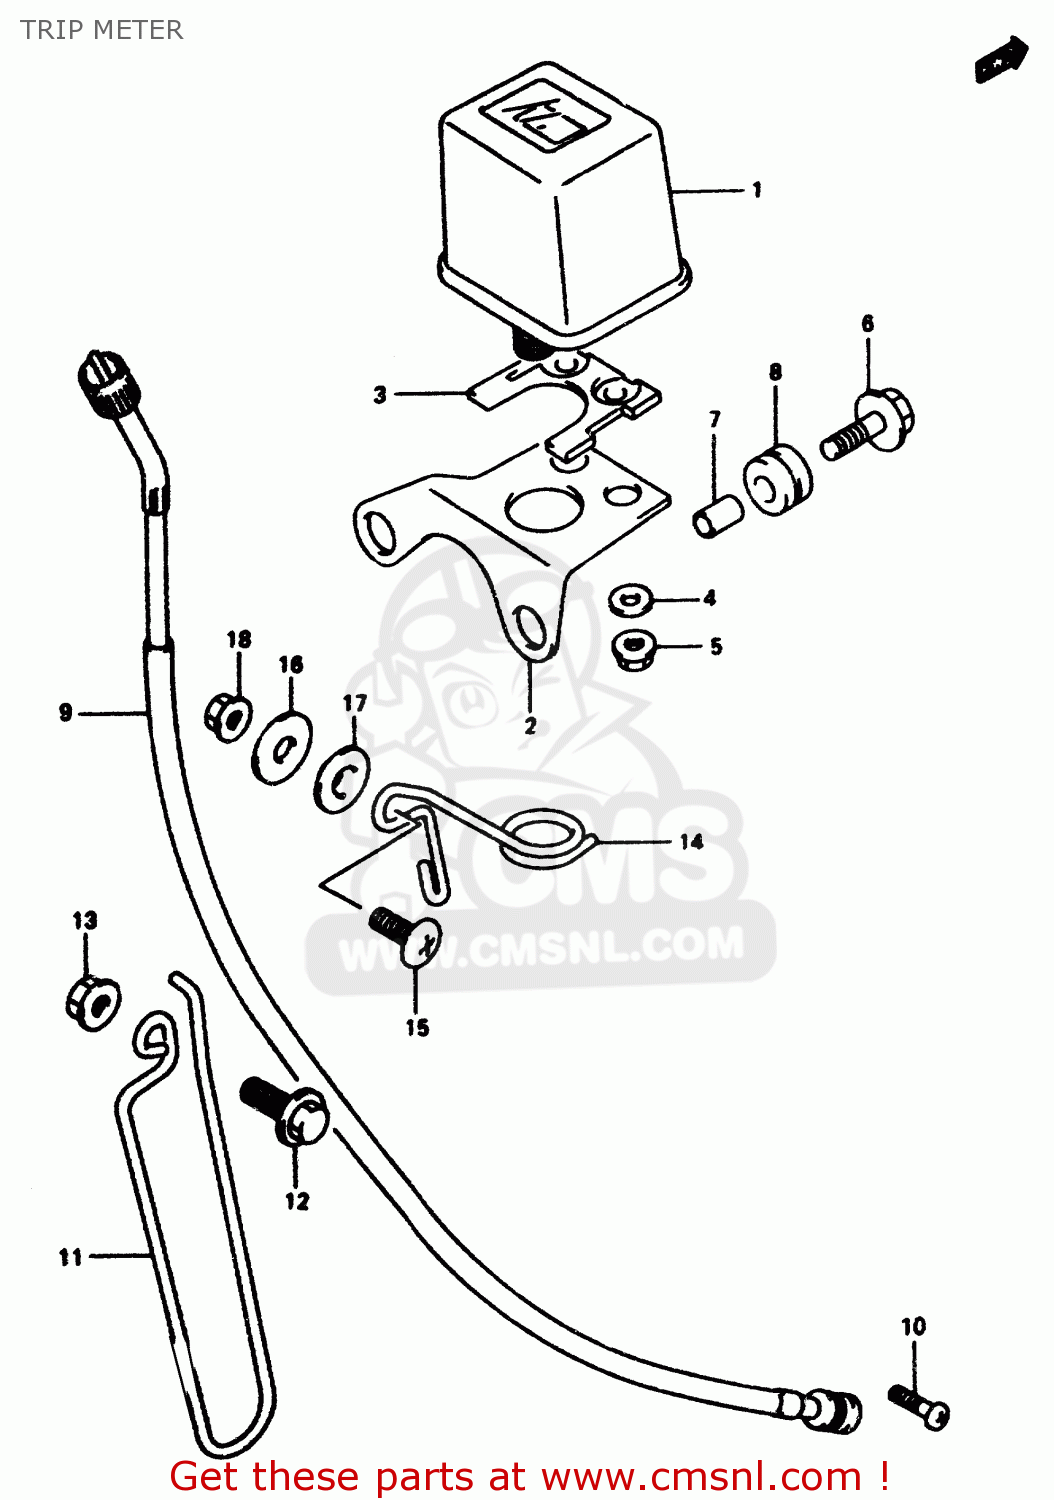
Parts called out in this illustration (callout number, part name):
1	TRIP METER
2	BRACKET
3	CUSHION
4	WASHER (4.3X13X0.80)
5	NUT
6	BOLT(6X25)
7	SPACER(6.1X8X9.5)
8	CUSHION
9	CABLE ASSY,SPEEDOMETER
10	SCREW
11	GUIDE,METER CABLE NO.2
12	BOLT(6X16)
13	NUT
14	GUIDE,METER CABLE NO.1
15	SCREW
16	WASHER(6.5X18X1.6)
17	WASHER
18	NUT 6MM
